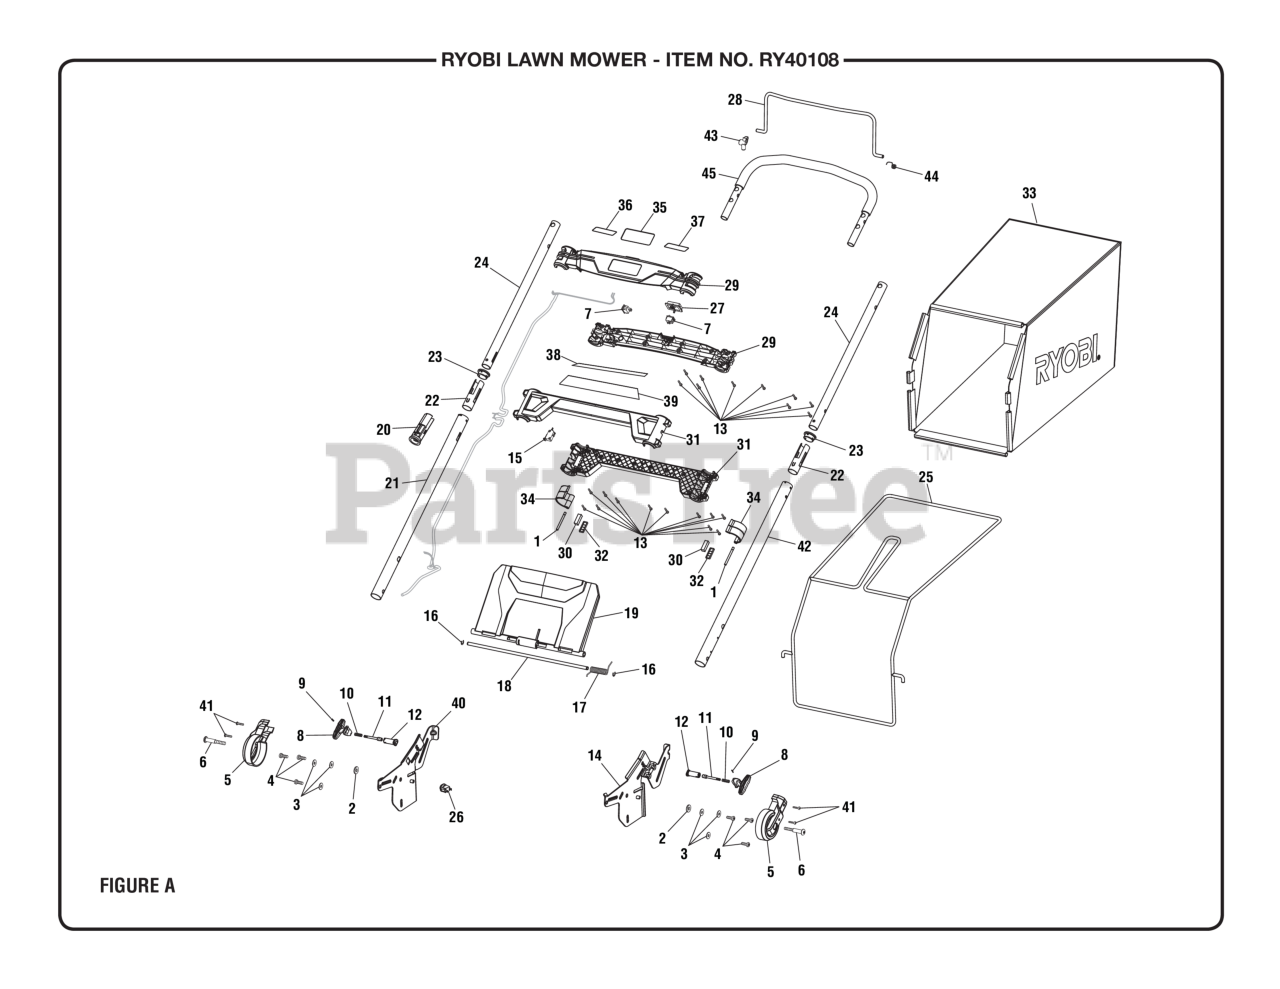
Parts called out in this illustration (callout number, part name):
1	Pin (Handle Lock Clip)
2	Washer (ID8.5 x OD20.5 x 2 mm x 2t)
3	Washer (1/4 in., Type A)
4	Screw (1/4-15 x 3/4 in., T30 Torx Pan Hd.)
5	Hinge Cover
6	Shoulder Screw (M8 x 60 mm, T40 Torx Hd.)
7	Stop Switch (Momentary Contact)
8	Adjustment Knob (Spring Pin)
9	Spring Pin
10	Compression Spring
11	Detent Pin
12	Spring Pin Housing
13	Screw (M4 x 18 mm, T20 Torx Pan Hd.)
14	Height Adjustment Bracket (Left)
16	RETAINING RING (EXTERNAL)
17	Torsion Spring (Rear Door)
18	Rear Door Axle
19	Rear Discharge Door
20	Switch Plug Housing
21	Lower Handle Tube (Right)
22	Handle Tube Bushing (Large)
23	Handle Tube Bushing (Small)
24	Upper Handle Tube
25	Bag Frame
26	TOGGLE SWITCH
27	Safety Switch Cover
28	Bail Handle
29	Upper Panel Assembly
30	Rubber Plate (Handle Lock Clip)
31	Lower Panel Assembly
32	Block (Handle Lock Clip)
34	Telescoping Latch
35	Logo Label
36	Start Label (Right)
37	Start Label (Left)
38	Lithium Label
39	Extended Handle Label
40	Height Adjustment Bracket (Right)
41	Screw (M4 x 20 mm, T20 Torx Pan Hd. S.T.)
42	Lower Handle Tube (Left)
43	Actuator Switch
44	Torsion Spring
45	Upper Handle & Foam Grip Assembly
